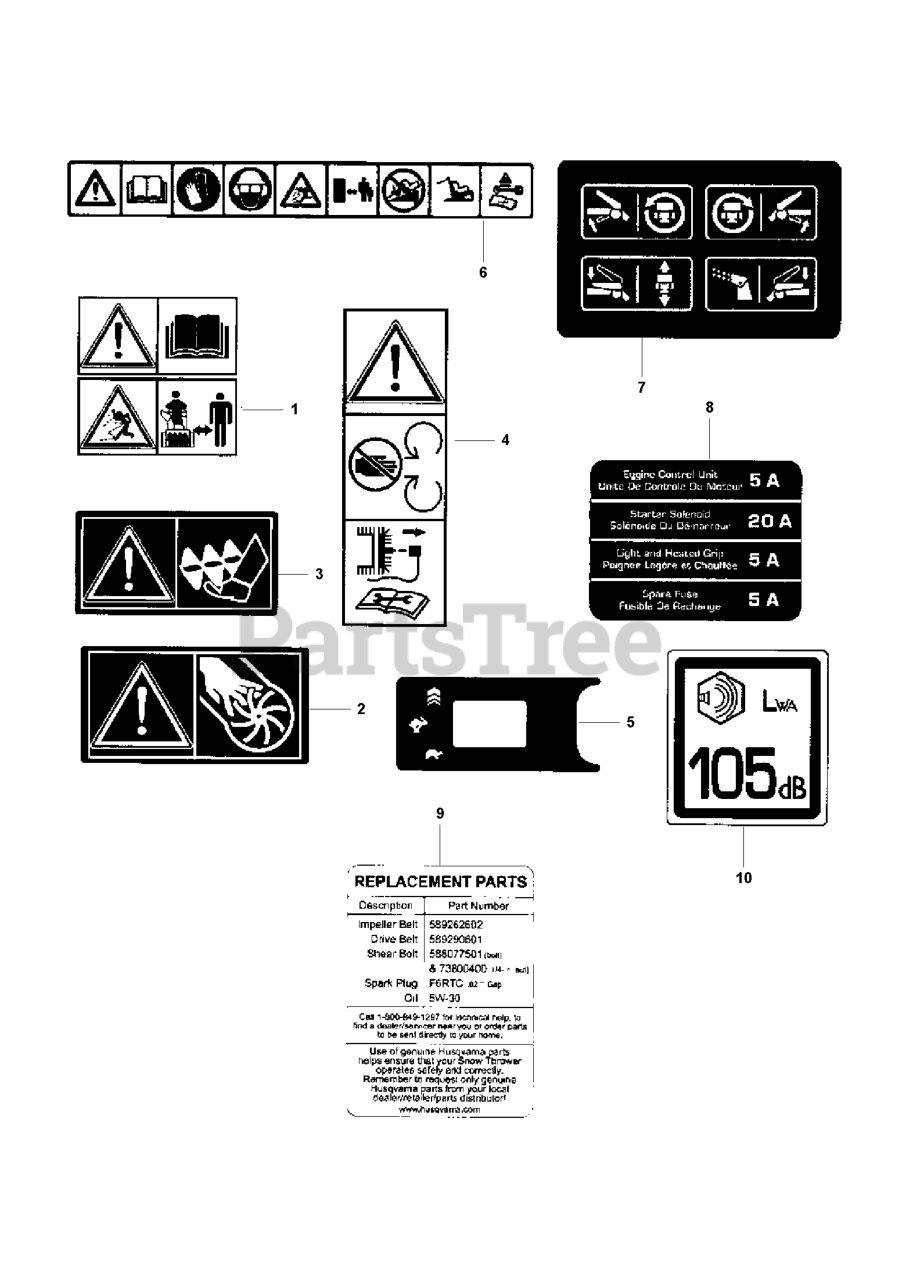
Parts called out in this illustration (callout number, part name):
1	DECAL.AUGER."
2	DECAL.CHUTE.SAFETY.EU/SC.17
3	DECAL.AUGER.SAFETY.
4	DECAL.BELT.GUARD.
5	DECAL SNOW CONSOLE GRAPHIC DEC
7	DECAL SNOW CONSOLE GRAPHIC DEC
8	DECAL SNOW BATTERY BOX GRAPHIC
9	DECAL SNOW BATTERY BOX GRAPHIC
10	DECAL.NOISE.LEV.105/CE.EAC.UKR
